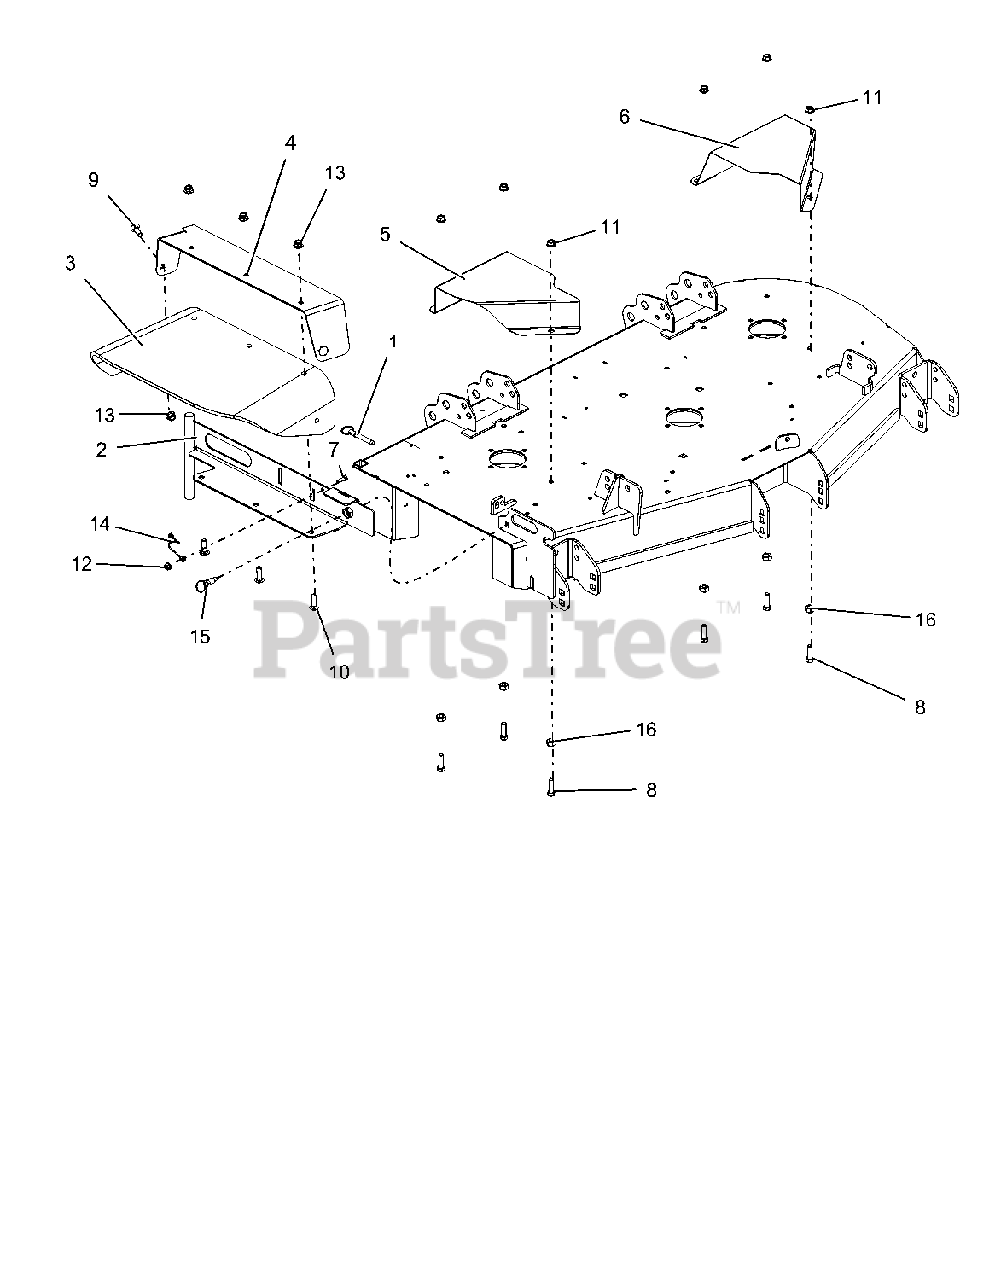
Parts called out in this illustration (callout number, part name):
1	PIN, SPRING BALL .375 OD X 1.50
2	WLDMT, DISCHARGE CHUTE 44"-48" (RED)
3	CHUTE, RUBBER DISCHARGE
4	SUPPORT, CHUTE MOUNTING BRKT
5	GUARD, DECK 44"-52" RH (RED)
6	GUARD, DECK 44-52" LH (RED)
7	BLT-HEX .25-20X.75 GR5 YWZC
8	BLT-HEX .38-16X1.25 GR5 YWZC
9	BLT-RDHDSQNK .38-16X1.00 G5 YWZC
10	BLT-RDHDSQNK .38-16X1.25 G5 YWZC
11	@NUT-SPNLK-FLG .375-16 YWZC
12	NUT, LK-TOP-FLG .25-20 YWZC
13	NUT-LK-NYL-FLG .38-16 YWZC
14	CABLE, 6.0 LANYARD, NYLON
15	PULL PIN,.50-13THDX.310 PLNGR
16	NUT-HEAVY HEX .38-16 YWZC
